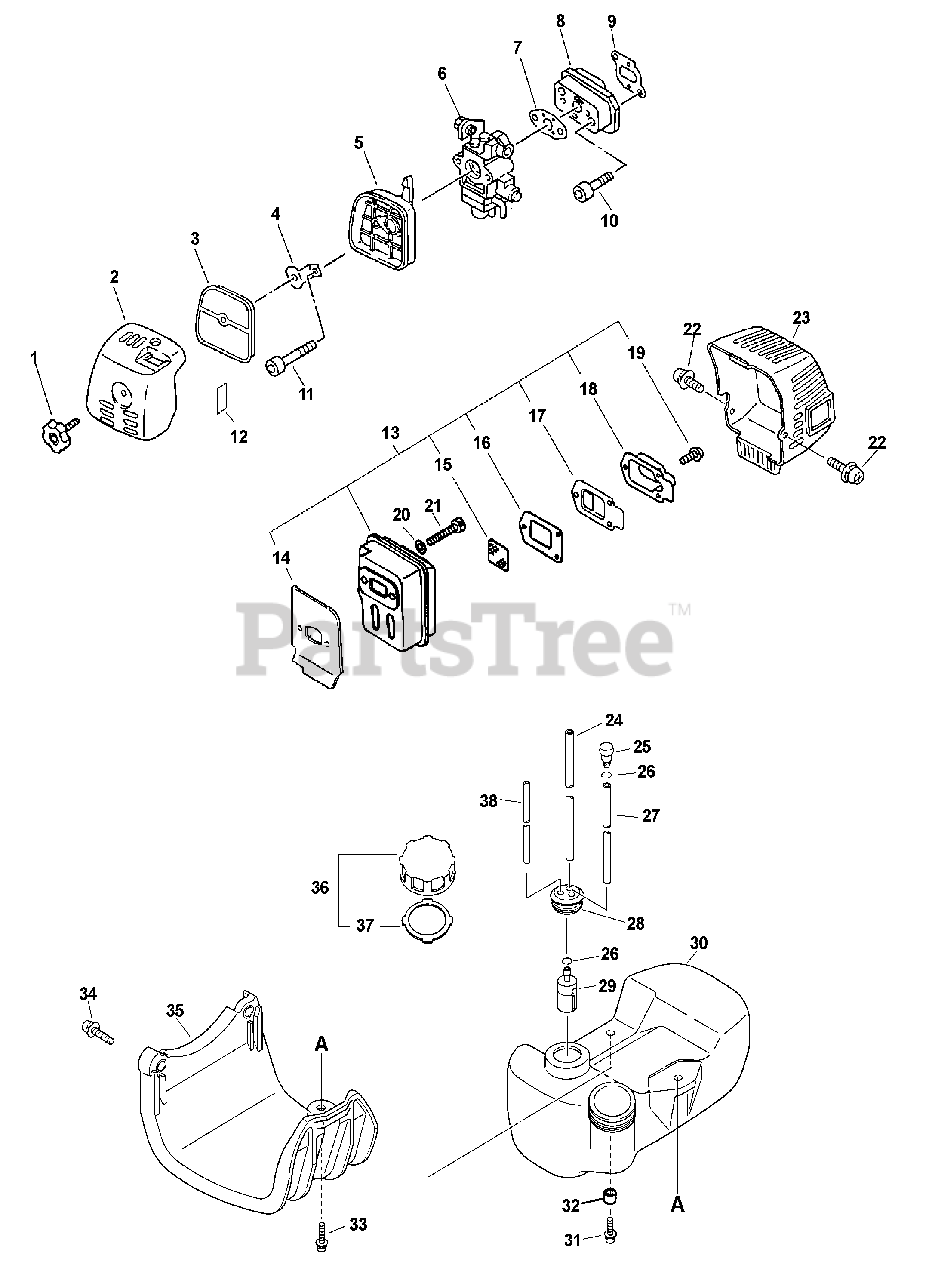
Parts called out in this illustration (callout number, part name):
1	THUMBSCREW
2	COVER, AIR FILTER
3	FILTER, HEAVY-DUTY AIR
4	PLATE, PREVENT
5	CASE, AIR FILTER
6	CARBURETOR - WYJ-192
7	GASKET, CARBURETOR
8	INSULATOR, INTAKE
9	GASKET, INTAKE
10	BOLT 5×25
11	SCREW 5×55
12	LABEL - CHOKE
13	MUFFLER ASSY
14	GASKET, EXHAUST
15	SCREEN, SPARK ARRESTER
16	GASKET, EXHAUST
17	GUIDE, EXHAUST
18	OUTLET, EXHAUST
19	SCREW 4×10
20	WASHER, FLAT 5.5×10×0.8
21	BOLT 5×55
22	BOLT 5×12
23	COVER, MUFFLER
24	PIPE, FUEL 3×6×170
25	VENT ASSY
26	CLIP Ø6.5 MM
27	PIPE, FUEL 3×6×100
28	GROMMET, FUEL
29	FILTER, FUEL
30	TANK, FUEL
31	SCREW 5×16
32	SPACER 6.2×7.8×6
33	SCREW 5×20
34	BOLT 5×22
35	GUARD, FUEL TANK
36	CAP ASSY, FUEL
37	GASKET, FUEL CAP
38	PIPE, FUEL 3×6×60 CLEAR
